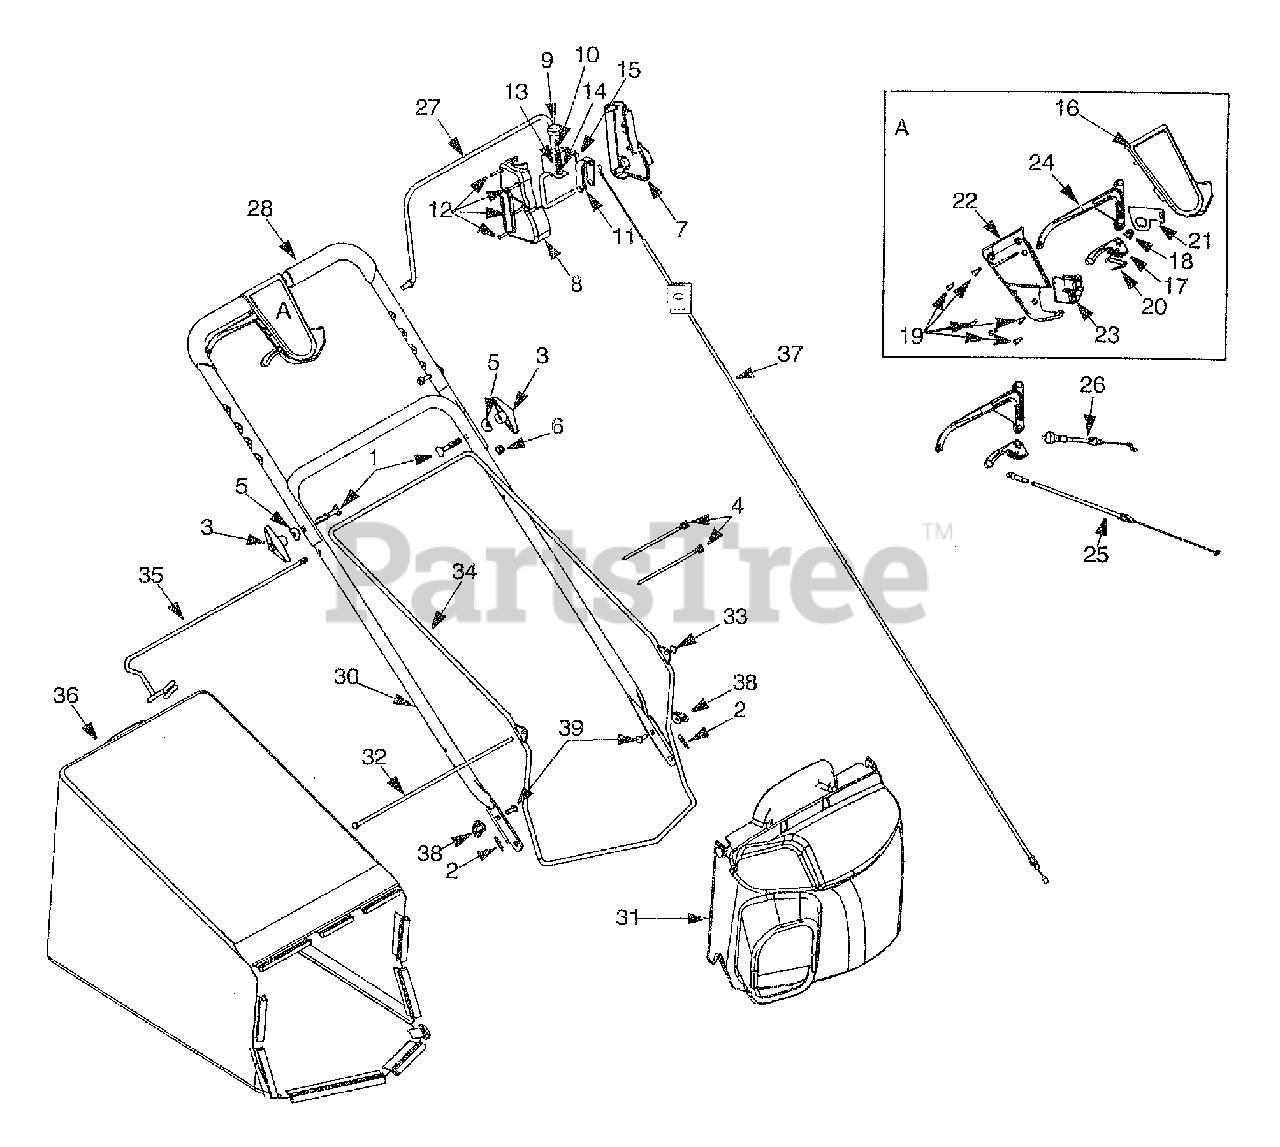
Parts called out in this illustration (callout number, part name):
1	Bolt Cur. Carr. 5/16-18 x 2.0
2	Cotter Pin .072 x 1.12 Lg.
3	Knob Ass'y Wing Nut 5/16-18
4	Cable Tie
5	Wash. Sad. .320 ID x.830 OD
6	Hex Nut 5/16
7	Control Cover LH
8	Control Cover RH
12	Hi-Low Screw
13	Compression Spring
14	Retention Spring
15	Torsion Spring
16	Upper Control Housing
17	6-Speed Shift Lever
18	Gear Insert
19	C-Sunk Tap Screw #10 x .75 L
20	Shift Lever Spring
21	6-Speed Rack Cable Brkt.
22	Lower Control Housing
23	Cable Mounting Cap
24	Control Lever
25	6-Speed Cable
26	Self-Propelled Cable
27	Control Handle
28	Foam Grip
31	Grassbag Cover w/Label
32	Pivot Rod
36	Grass Bag
37	Control Cable 58.25"
38	Wing Nut
39	Carriage Bolt 1/4-20
